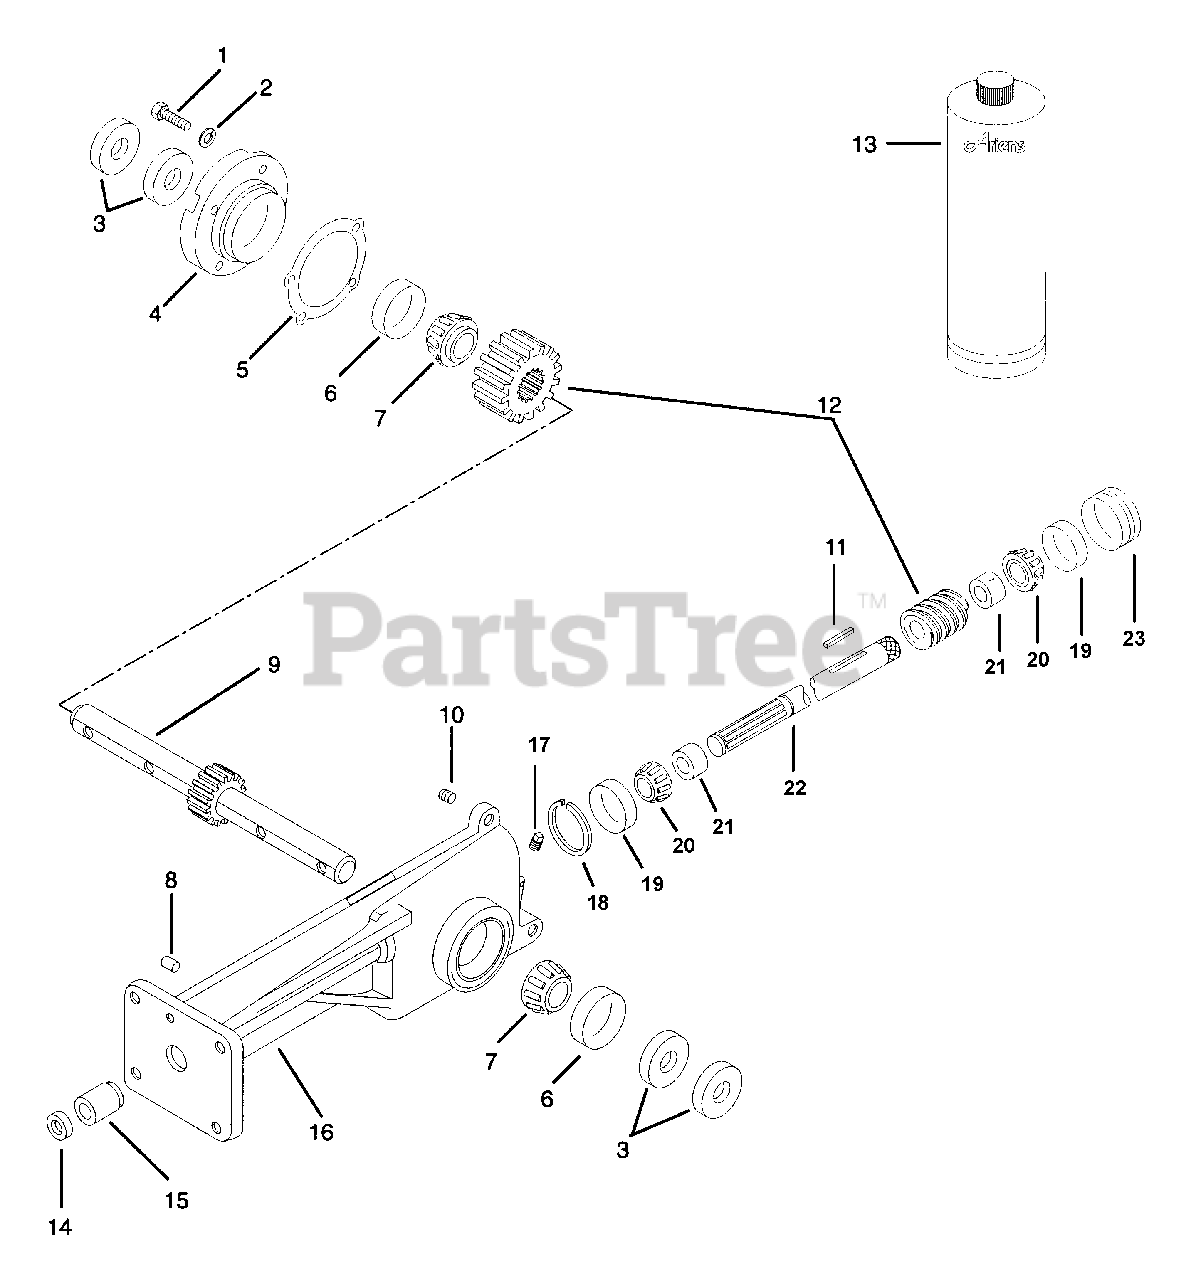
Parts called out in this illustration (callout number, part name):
1	BLT-HEX .38-16X1.00 PL GR5
2	WSHR-LK .375X.115 HVY PL
3	SEAL 1.250X2.00X.250
4	BEARING FLANGE
5	SERVICE KIT
6	BRG-CUP 2.328X.465
7	BRG-CONE 1.25X.66
8	BREATHER
9	TINE SHAFT
10	SCR-SET .25-20X.25 SKHCUPDL
11	KEY-WDRF .188X1.00X.438 SAE13
12	WORM AND WORM GEAR ASSEMBLY
13	ARIENS 16 OZ.BOTTLE OF L2 LUBE
14	SEAL .750X1.000X.125
15	BRG-NEEDLE .750X1.0X.62
16	TILLER GEARCASE - C.I.
17	PIPE PLUG
18	RG-RTNG-INT 1.781X.062
19	BRG-CUP 1.781X.475
20	BRG-CONE .750X.61
21	BSHG, SPCR .755X1.12X.50 PM
22	WORM SHAFT
23	ADJUSTMENT PLUG
